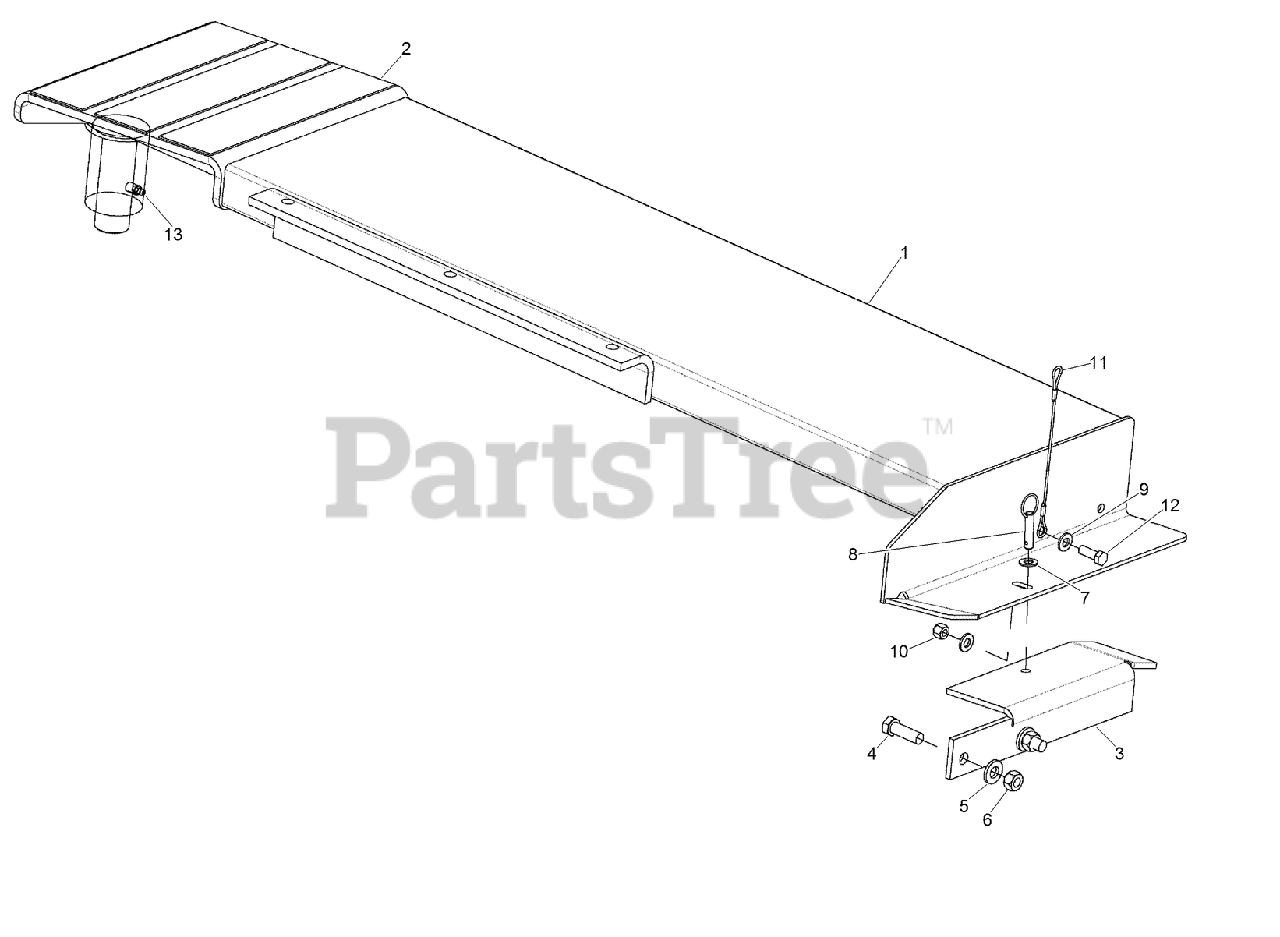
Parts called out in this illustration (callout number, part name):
1	CATWALK - Backhoe Attachment
2	TAPE-ANTI SKID, CATWALK
3	ANGLE - Walkway Support
4	SCREW-HH
5	WASHER-FLAT
6	NUT-LOCK, HEX
7	WASHER-0.406 x 0.812 x 0.065 in CST ZND
8	PIN-Cotterless
9	WASHER-FLAT
10	NUT
11	RETAINER-ROPE, WIRE
12	SCREW-HH
13	FITTING-Lube 1/4-28 Tpr SAE-LT .54 Long
